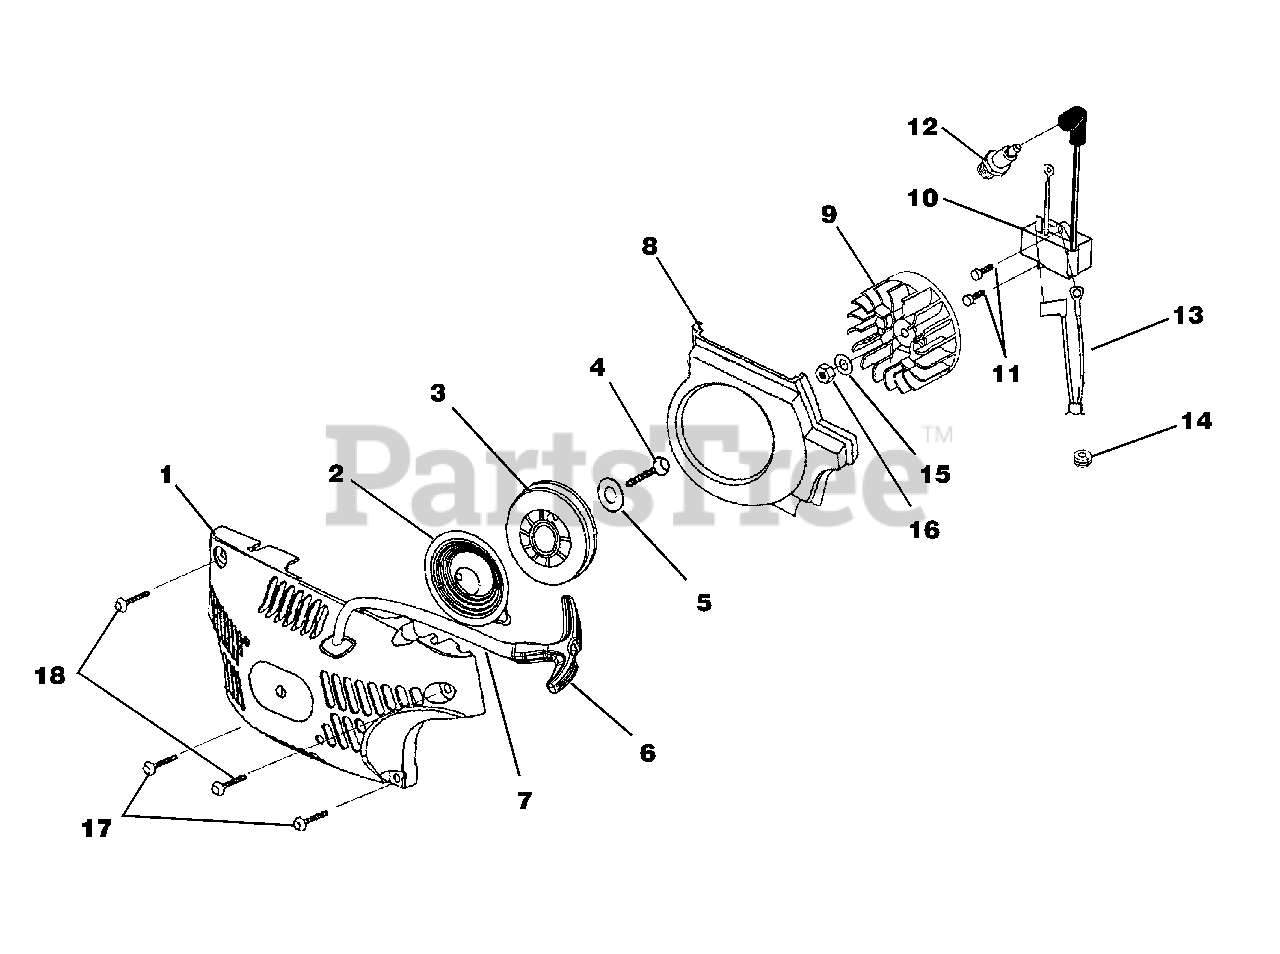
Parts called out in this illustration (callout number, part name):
1	Starter Kit
2	Spring & Container
3	Pulley, Starter
4	Screw, Thread Form, Plastite (10-14 x 5/8")
5	Washer, Retaining
6	Grip, Starter
7	Rope, Starter 46"
8	Baffle, Fan Housing
9	Rotor & Starter Pawl
10	Ignition Kit
11	Screw, Thread Form (8-32 x 5/8")
12	Spark Plug
13	Ignition Switch Harness
14	Grommet, Wire Harness (Split)
15	Washer, Flat
16	Nut, Jam
17	Screw, Truss Hd., Plastite (10-14 x 7/8")
18	Screw, Truss Hd., Plastite (10-14 x 5/8")
